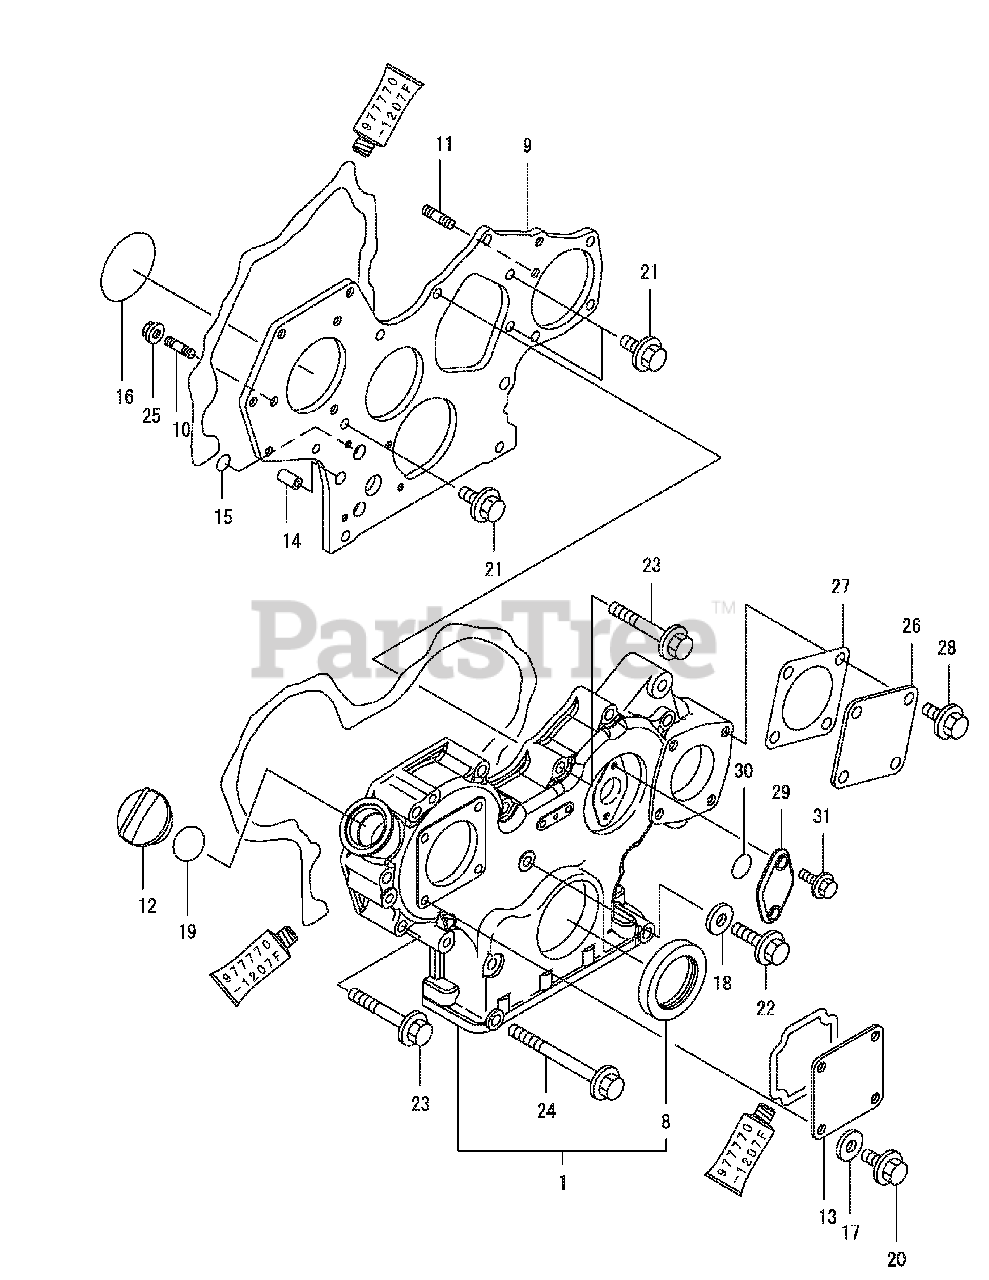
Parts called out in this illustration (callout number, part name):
1	Gear Housing Assembly
9	Gear Case Flange
16	O-Ring, F.I. Pump
17	Seal Washer, 8S
18	Seal Washer, 8S
19	O-Ring, 1A P-32.0
29	Tachometer Cover
30	O-Ring, 1A S-24.0
